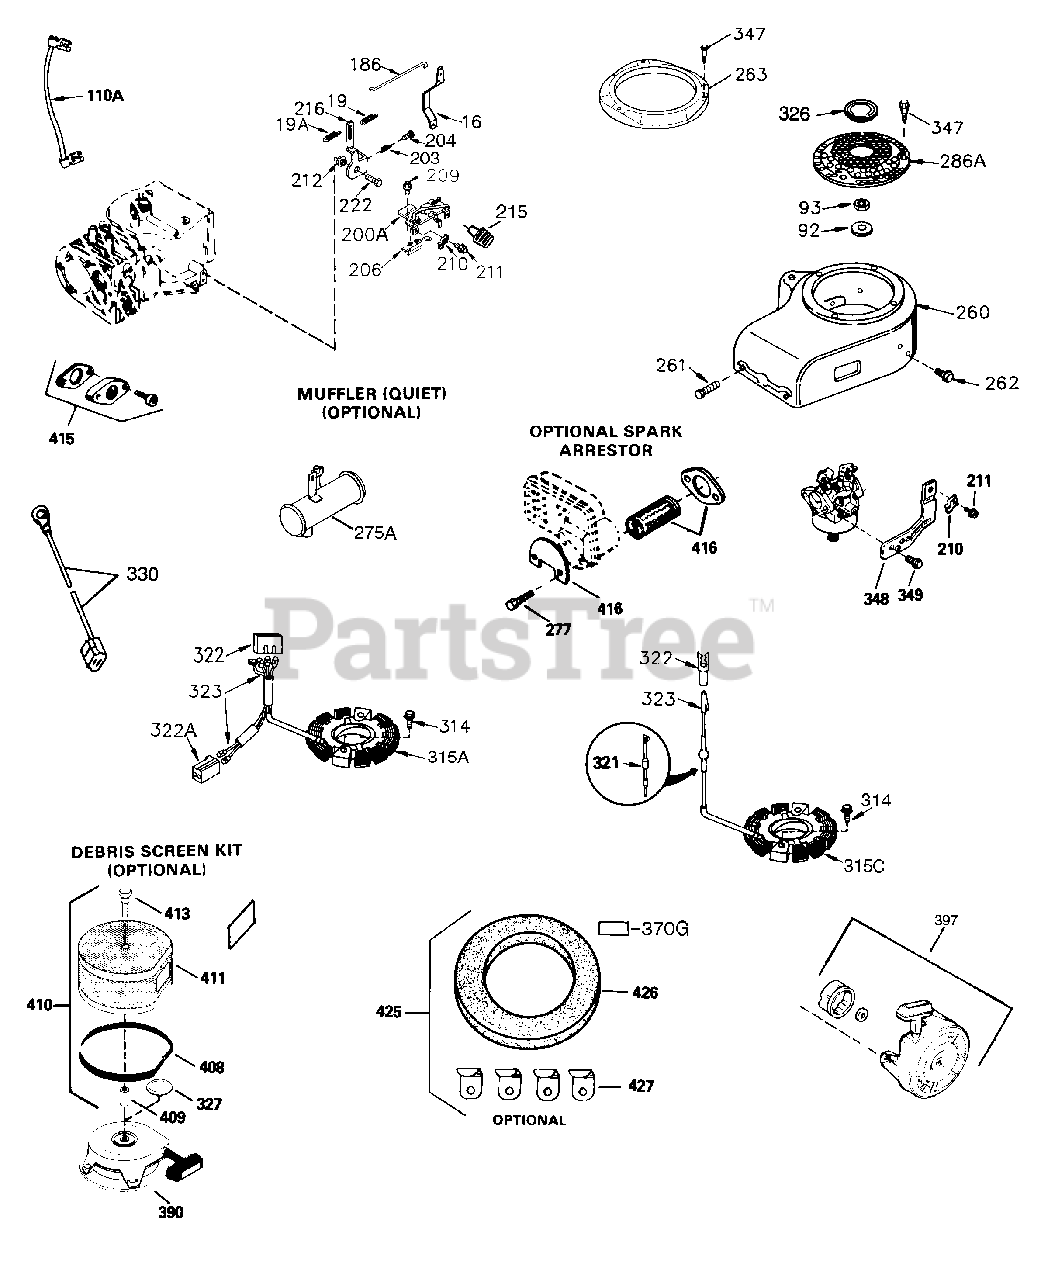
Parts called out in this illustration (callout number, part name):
16	Governor Lever
19A	Extension Spring
64	Screw, 5/16-18 x 15/32"
92	Lock Washer
93	Flywheel Nut
186	Governor Link
203	Compression Spring
204	Screw, 6-32 x 21/32"
206	Terminal
209	Screw, 10-24 x 9/16"
215	Control Knob
251A	Nut & Lock Washer, 1/4-20
260	Blower Housing
261	Screw, 5/16-18 x 3/4"
262	Screw, T-40, 5/16-24 x 21/32"
277	Screw, 5/16-18 x 3-3/16"
314	Screw, 1/4-20 x 3/4"
322	Connector Body
322A	Connector Body
323	Terminal
327	Starter Plug
390	Rewind Starter Note: This engine cou ld have been built with 590704 starte r. Refer to the design of the air int ake louvers for part identification. Individual starter parts do not inter change.
